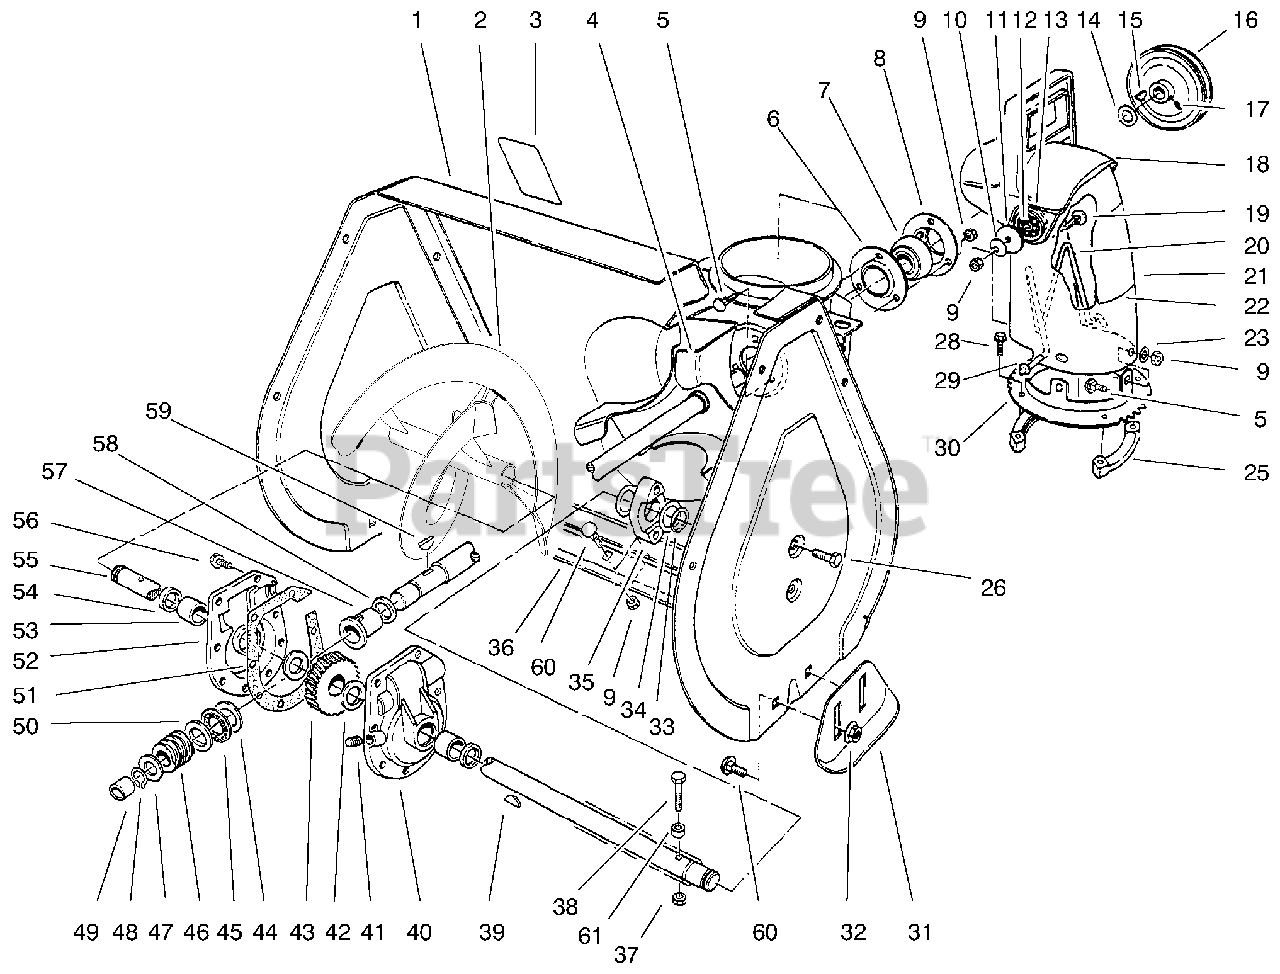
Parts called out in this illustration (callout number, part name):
1	Housing-Auger (Incl. Ref. #3)
2	Auger-R.H.
3	Decal-Auger Warning
4	Shaft & Impeller
5	Bolt-Carriage
6	Flange-Bearing Front
7	Bearing-Ball
8	Flange-Bearing Rear
9	Nut-Lock
10	Washer-Lock
11	Washer-Flat
12	Plate-Friction
13	Washer-Rubber
17	Screw-Set
18	Deflector
19	Bolt-Carriage
20	Chute-Wire
21	Chute-Discharge (Incl. Ref.# 22)
22	Decal-Discharge
25	Retainer-Chute Ring
26	Screw-Self Tapping
28	Screw-Self Tapping
30	Ring-Chute
32	Nut-Flange
33	Ring-Retaining
34	Washer-Thrust
35	Bearing-Auger
36	Blade-Scraper
37	Nut-Lock
39	Key-Woodruff
40	Gear Case L.H. (Incl. Ref. #53 & 54)
41	Pipe-Plug
42	Bearing-Thrust
44	Washer-Thrust
45	Bearing-Needle, Thrust
46	Gear-Worm
48	Ring-Retaining
49	Bushing
50	Washer-Thrust
52	Gear Case R.H. (Incl. Ref. #53 & 54)
54	Seal-Oil
55	Shaft-Auger
56	Screw-Self Tapping
57	Bushing-Input
59	Key-Woodruff
60	Bolt-Carriage
61	Spacer-Auger
